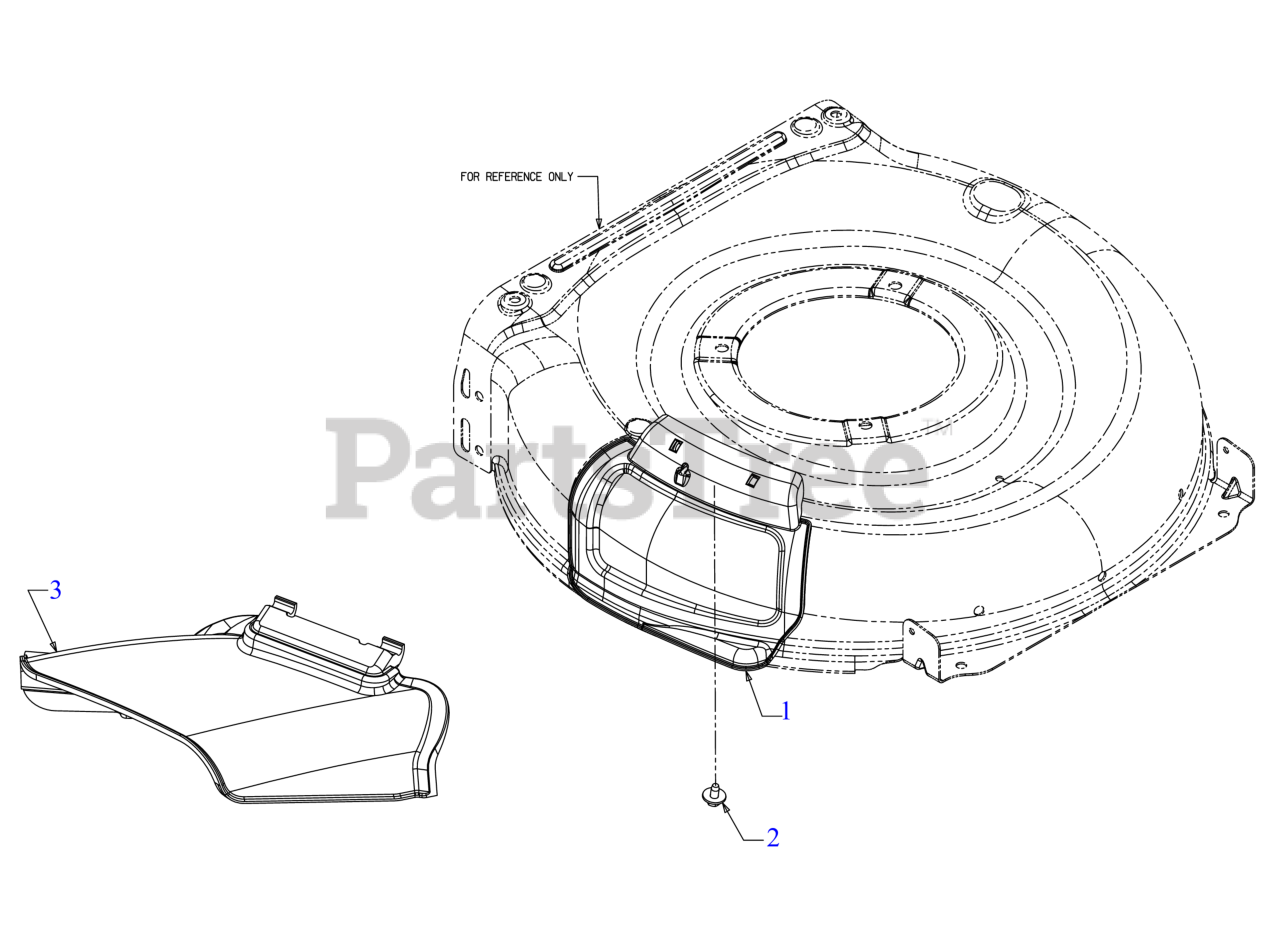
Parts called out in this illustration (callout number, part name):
1	MULCH PLUG ASSEMBLY
2	SCREW 1/4-20 x .50
3	SIDE DISCHARGE CHUTE
